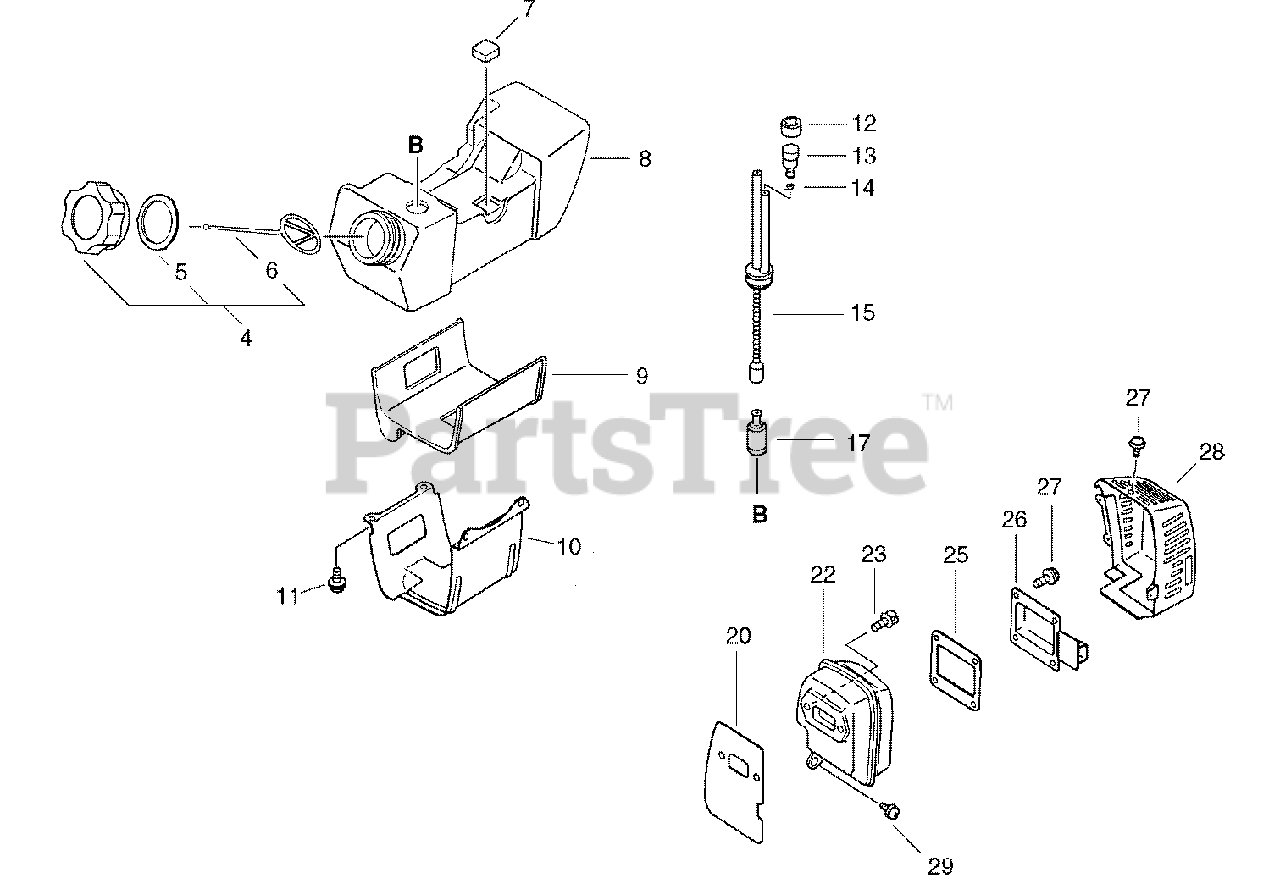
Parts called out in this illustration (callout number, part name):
4	CAP ASSY, FUEL
5	GASKET, FUEL CAP
6	CONNECTOR, CAP
8	TANK, FUEL
10	BRACKET, FUEL TANK
11	SCREW 5×14
12	HOLDER, VENT
13	VENT ASSY
14	CLIP 6.5 MM
15	PIPE, FUEL
17	FILTER, FUEL
20	GASKET, MUFFLER
23	BOLT 5×20
25	GASKET, EXHAUST
26	GUIDE, EXHAUST
27	SCREW 4×10
28	COVER, MUFFLER
29	SCREW 5×14
